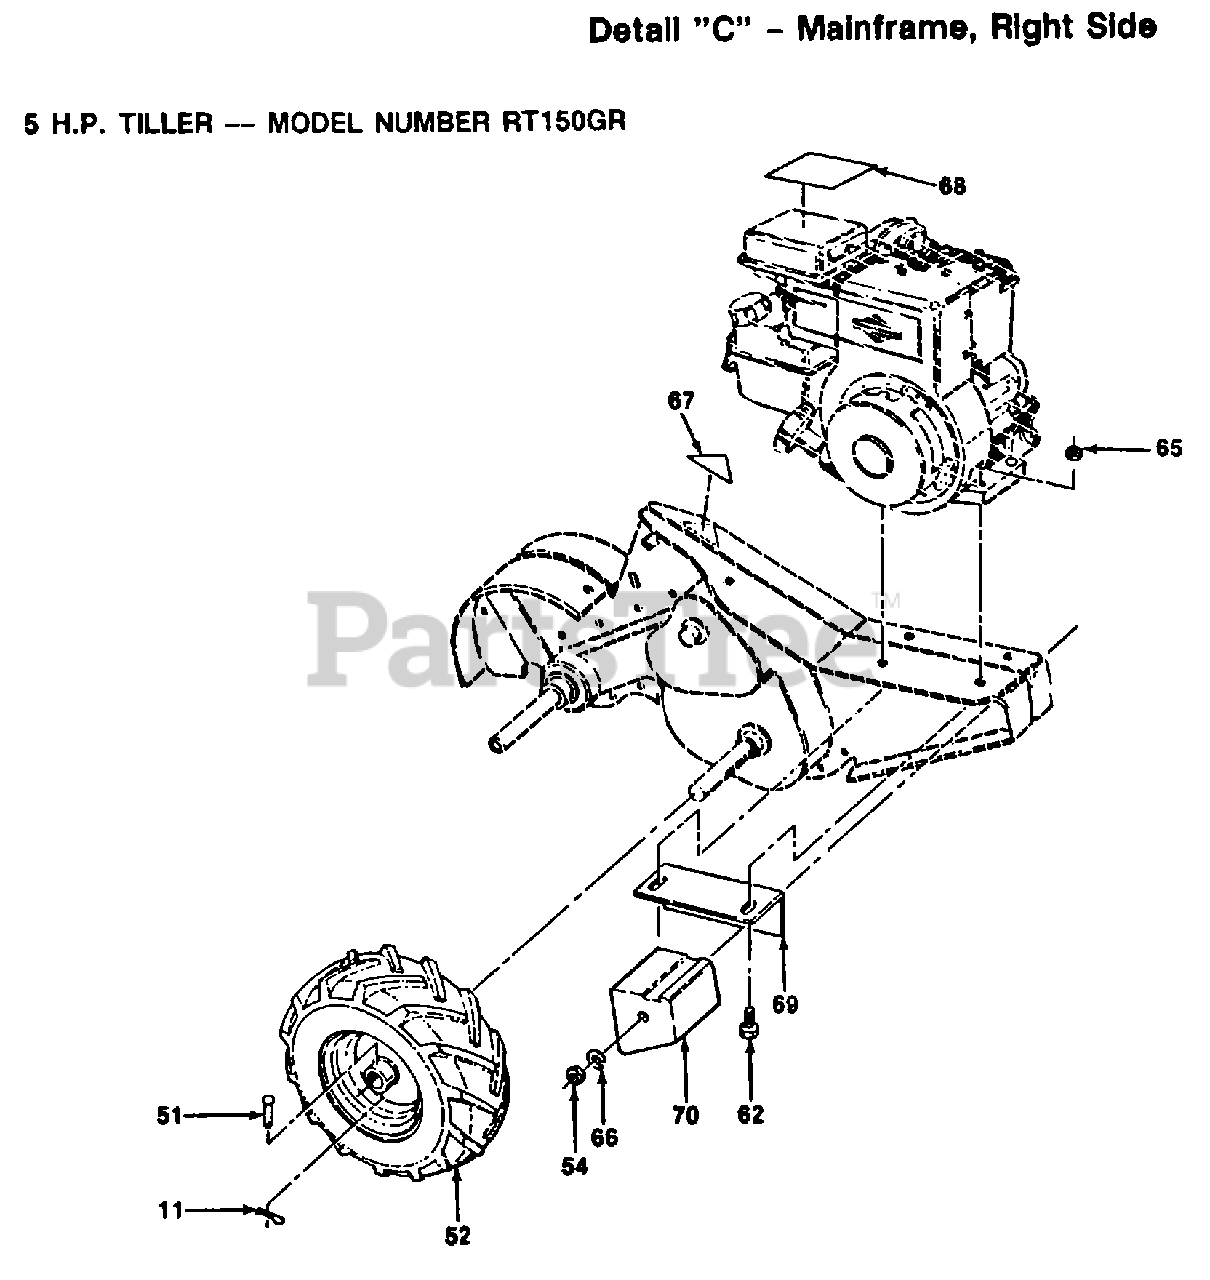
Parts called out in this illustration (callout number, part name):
11	RETAINER M
54	NUT.HEX.3/8-16UNC
62	BOLT.HEX.5/16-1.5
66	LOCKWASHER
68	DECAL TI
69	BRACKET RH CRT
70	COUNTERWEIGHT CRT
